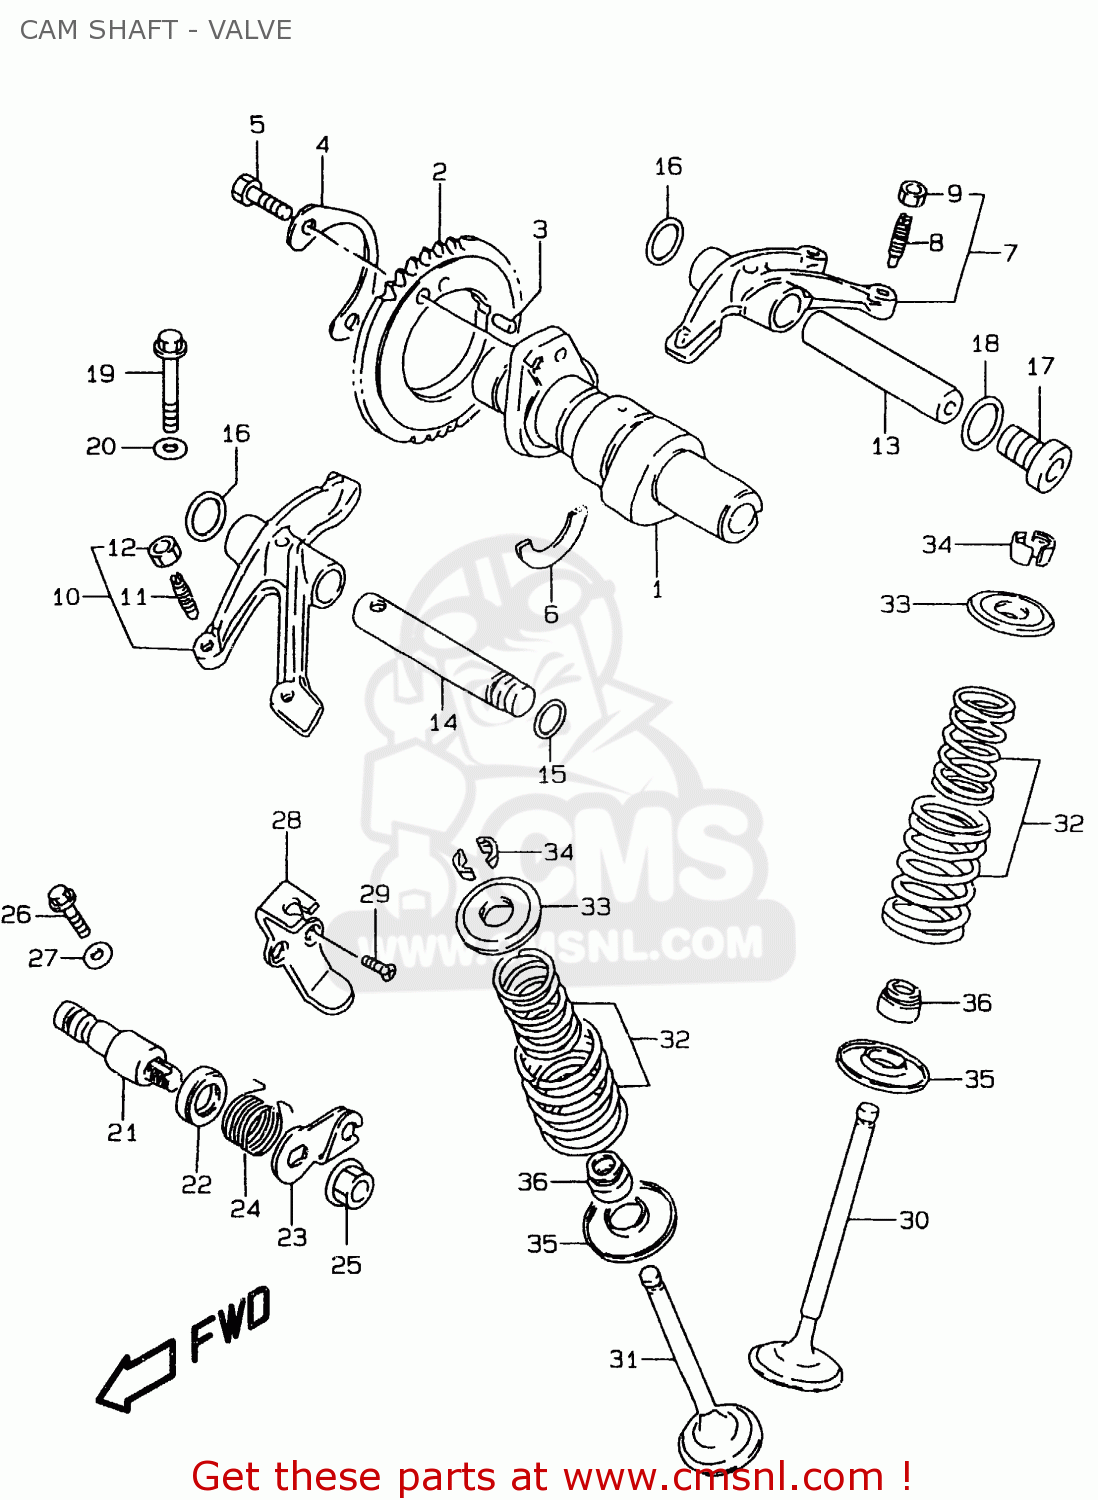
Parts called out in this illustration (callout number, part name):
1	CAMSHAFT
2	SPROCKET,CAMSHAFT
3	PIN(5X12.9)
4	WASHER,CAM CHAIN SPROCKET
5	BOLT(6X16)
6	C RING
7	ARM,VALVE ROCKER,INTAKE
8	SCREW,TAPPET ADJUSTING
9	NUT,ADJUSTING SCREW
10	ARM,VALVE ROCKER,EXHAUST
11	SCREW,TAPPET ADJUSTING
12	NUT,ADJUSTING SCREW
13	SHAFT,VALVE ROCKER ARM INTAKE
14	SHAFT,EXHAUST VALVE ROCKER ARM
15	O RING(D:1.9,ID:8.6)
16	WASHER
17	PLUG,14X12
18	GASKET(13.8X18.8X4.8) (NAS)
19	BOLT
20	GASKET(5.8X13X1.2) (NAS)
21	SHAFT,DECOMP,L
22	SEAL,OIL(10X20X6)
23	LEVER,DECOMP SHAFT,L
24	SPRING
25	NUT
26	BOLT(6X16)
27	GASKET(5.8X13X1.2) (NAS)
28	HOLDER,DECOMP CABLE,L
29	SCREW
30	VALVE,INTAKE
31	VALVE,EXHAUST
32	SPRING SET,VALVE
33	RETAINER,VALVE SPRING
34	COTTER,VALVE
35	SEAT,VALVE SPRING
36	SEAL,OIL(7X14.4X9)
